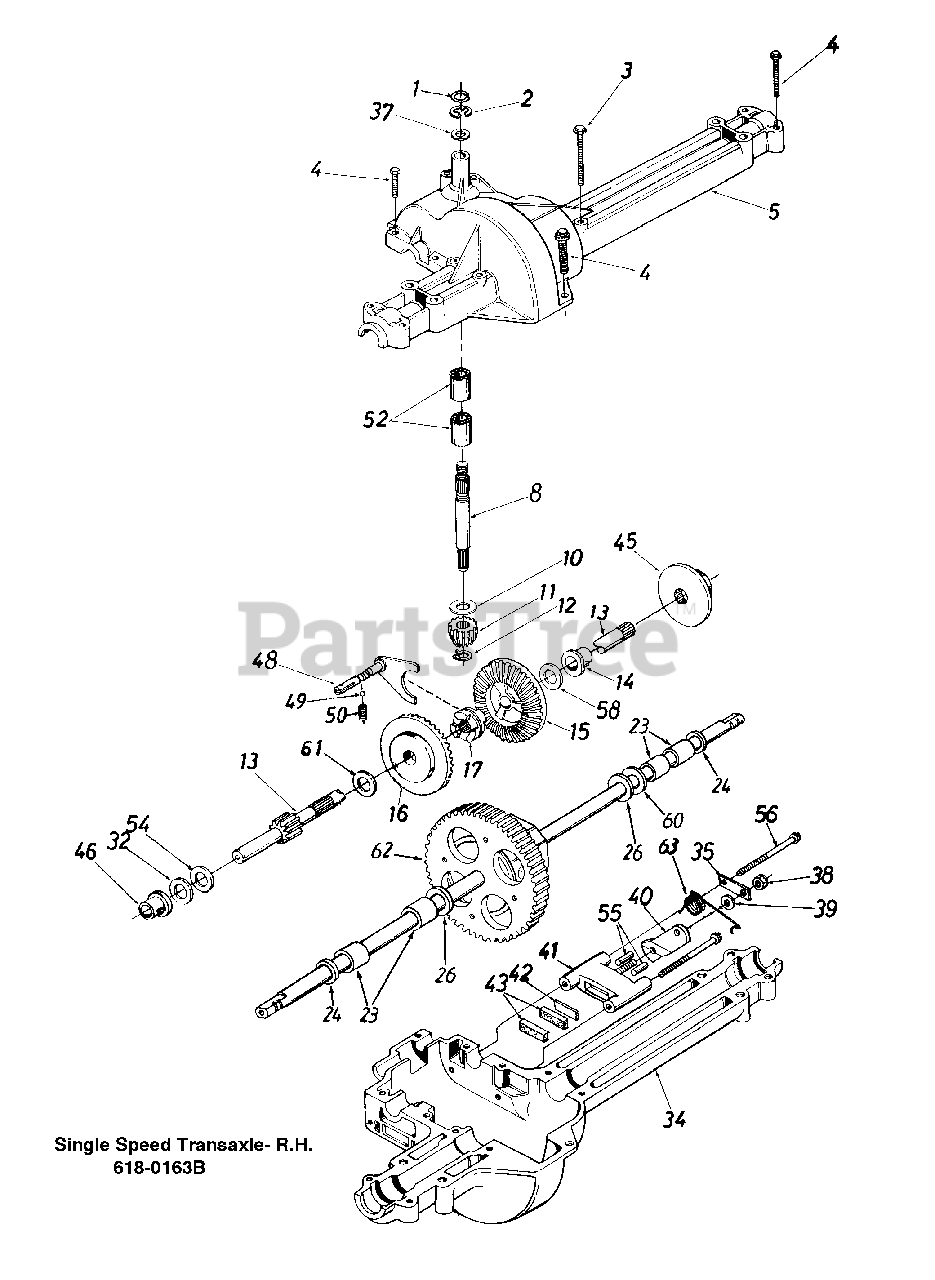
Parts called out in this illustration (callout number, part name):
3	Hex Wash. TT-Tap Scr. 1/4-20 x 1.75" Lg.
4	Hex Tap Scr. 1/4-20 x 1.25" Lg.
5	Upper Housing
10	Thrust Washer 5/8" I.D. x 1.25" O.D.
11	Pinion Input 14T
12	Retaining Ring
13	Drive Shaft-R.H. Brake
14	Flange Brg. 5/8" I.D. x 3/4" Lg.
15	Bevel Gear 42T Small I.D.
16	Bevel Gear 42T Large I.D.
17	Clutch Collar
23	Sleeve Bearing 3/4" I.D. x 1.0" Lg.
24	Oil Seal 3/4" I.D.
26	Fl-Wash. .760" I.D. x 1.5" O.D.
32	Thrust Wash. 5/8" I.D. x 1" O.D. x .025" Thk.
34	Lower Housing
35	Anti-Rotation Brkt.
37	Fl-Wash. 5/8" I.D. x 1" O.D. x .020" Thk.
38	Hex Nut 5/16-24 Thd.
39	Fl-Wash. .344" I.D. x .875" O.D.
40	Actuating Arm
41	Brake Yoke
42	Puck Plate
43	Brake Puck
46	Flange Bearing 5/8" I.D. x 15/16" Lg.
48	Shift Fork Ass'y.
49	Ball Detent .250" Dia.
50	Spring Detent
52	Needle Brg. 5/8" I.D. x 1/2" Lg.
54	Fl-Wash. 5/8" I.D. x 1" O.D.x .020 Thk.
55	Actuating Pin 5/16" Dia.
56	Hex Wash Hd. Self-Tap Scr. 1/4-20 Thd.
58	Fl-Wash. 5/8" I.D. x 1" O.D. x .020 Thk.
60	Fl-Wash. .76" I.D. x 1.5" O.D. x .010" Thk.
61	Thrust Washer
62	Differential Ass'y.
63	R.H.-Brake Spring
618-0163B	Single Speed Transaxle - R.H.
